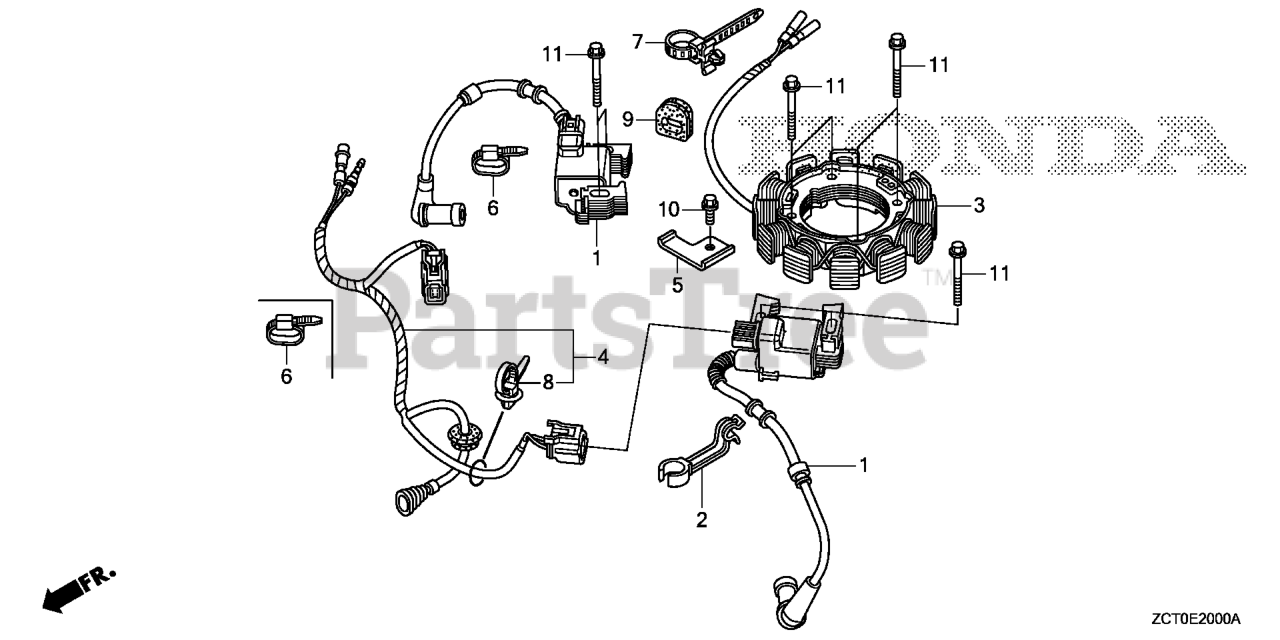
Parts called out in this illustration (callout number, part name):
1	COIL ASSY., IGNITION
2	CLAMP, IGNITION WIRE
3	COIL ASSY., CHARGE (17A)
4	WIRE HARNESS ASSY., ENGINE
5	BRACKET, HARNESS
6	BAND, WIRE (95MM)
7	STRAP, CABLE (105MM) *NH1* (Honda Code 1685536). (BLACK)
8	CLIP, HARNESS BAND (145MM) (BLACK)
9	GROMMET, CORD
10	BOLT, FLANGE (6X12) Use up to Engine SN 1543277.
11	BOLT, FLANGE (6X32)
